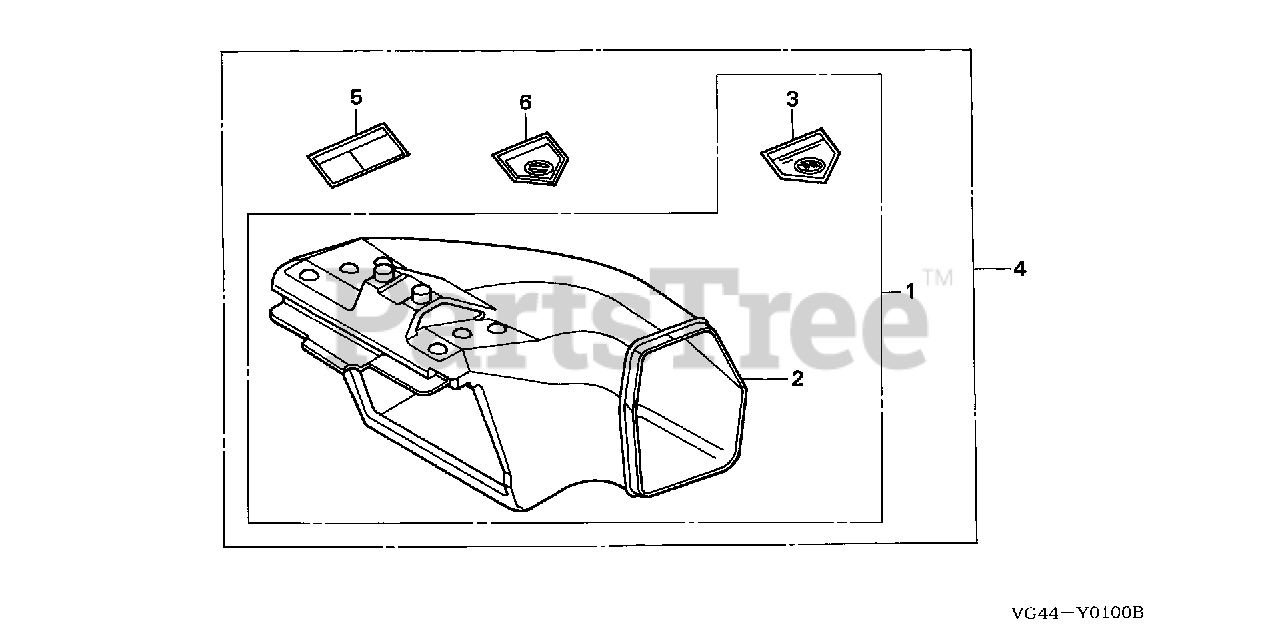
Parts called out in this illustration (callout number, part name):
1	CHUTE KIT, SIDE DISCHARGE
2	CHUTE KIT, SIDE DISCHARGE
3	CAUTION C, HOUSING
